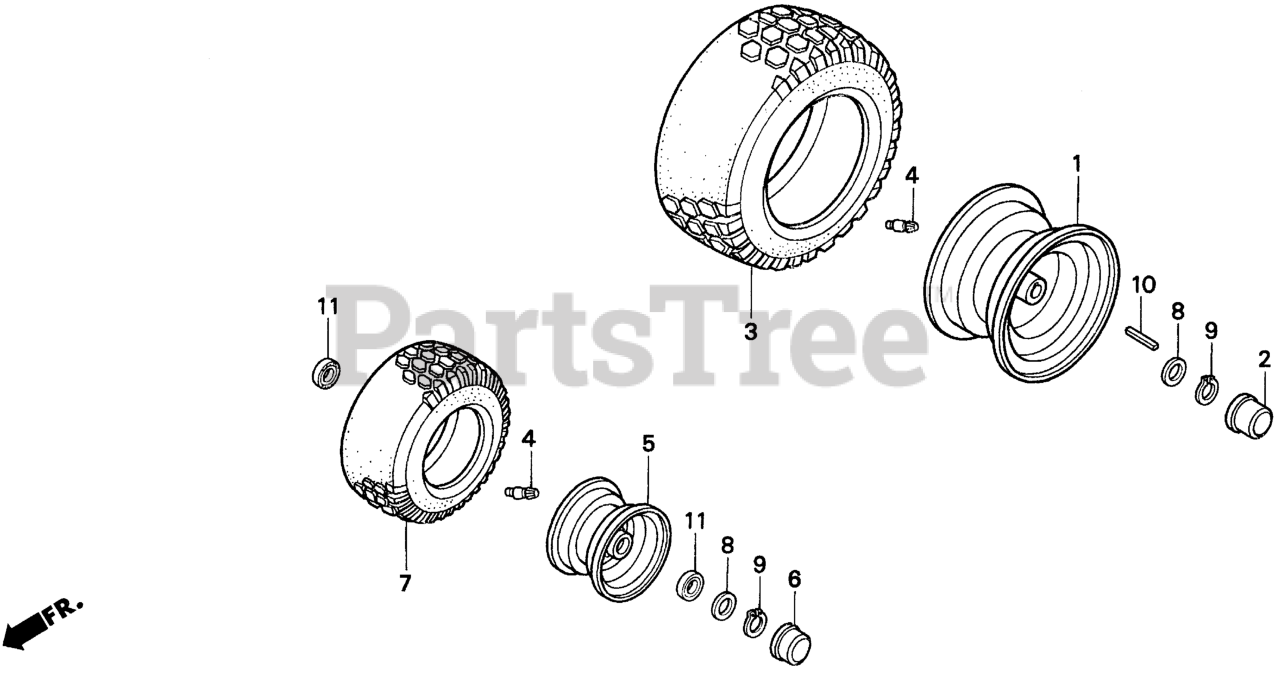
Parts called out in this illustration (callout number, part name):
1	WHEEL, RR.
2	CAP, RR. WHEEL
3	TIRE, RR. TUBELESS (16X6.50-8NHS) (GOODYEAR)
4	VALVE (TR-412)
5	WHEEL, FR.
6	CAP, FR. WHEEL
7	TIRE, TURF (11X4.00-5)
8	PLATE, PILLION STEP SIDE
9	CIRCLIP, EX. (3/4")
10	KEY (3/16")
11	BEARING, RADIAL BALL
